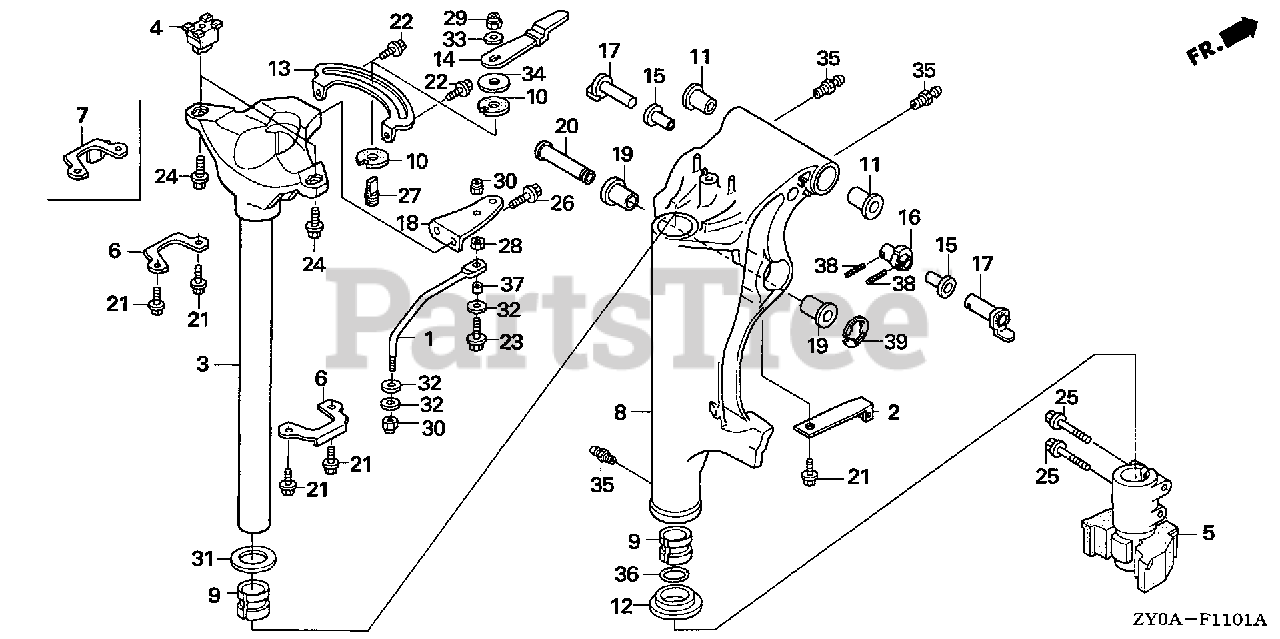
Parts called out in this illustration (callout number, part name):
2	SPRING, CLICK
3	FRAME, MOUNTING (S)
4	RUBBER, MOUNTING (UPPER)
5	RUBBER, MOUNTING (LOWER)
6	COVER, MOUNTING RUBBER (UPPER)
7	COVER, MOUNTING RUBBER (UPPER) (PT)
8	CASE, SWIVEL *NH282MU* (S)(PT) (OYSTER SILVER METALLIC-U)
9	LINER, SWIVEL CASE
10	BLOCK, FRICTION
11	BUSH, SWIVEL CASE
12	COLLAR, SWIVEL CASE
13	PLATE, FRICTION
14	LEVER, FRICTION
15	BUSH, TILT ARM
16	BRACKET, TILTING
17	STOPPER, TILT
19	BUSH, CYLINDER (LOWER)
20	PIN, CYLINDER (UPPER)
21	BOLT, FLANGE (6X12)
22	BOLT, FLANGE (6X12)
24	BOLT, FLANGE (10X25)
25	BOLT, FLANGE (8X45)
27	BOLT, STUD (8X26)
29	NUT, SELF-LOCK (8MM)
31	WASHER, THRUST
33	WASHER (8MM)
34	WASHER, NYLON (8MM)
35	NIPPLE, GREASE
36	O-RING (34X2.4)
38	PIN, SPRING (2.5X20)
39	E-RING (15MM)
